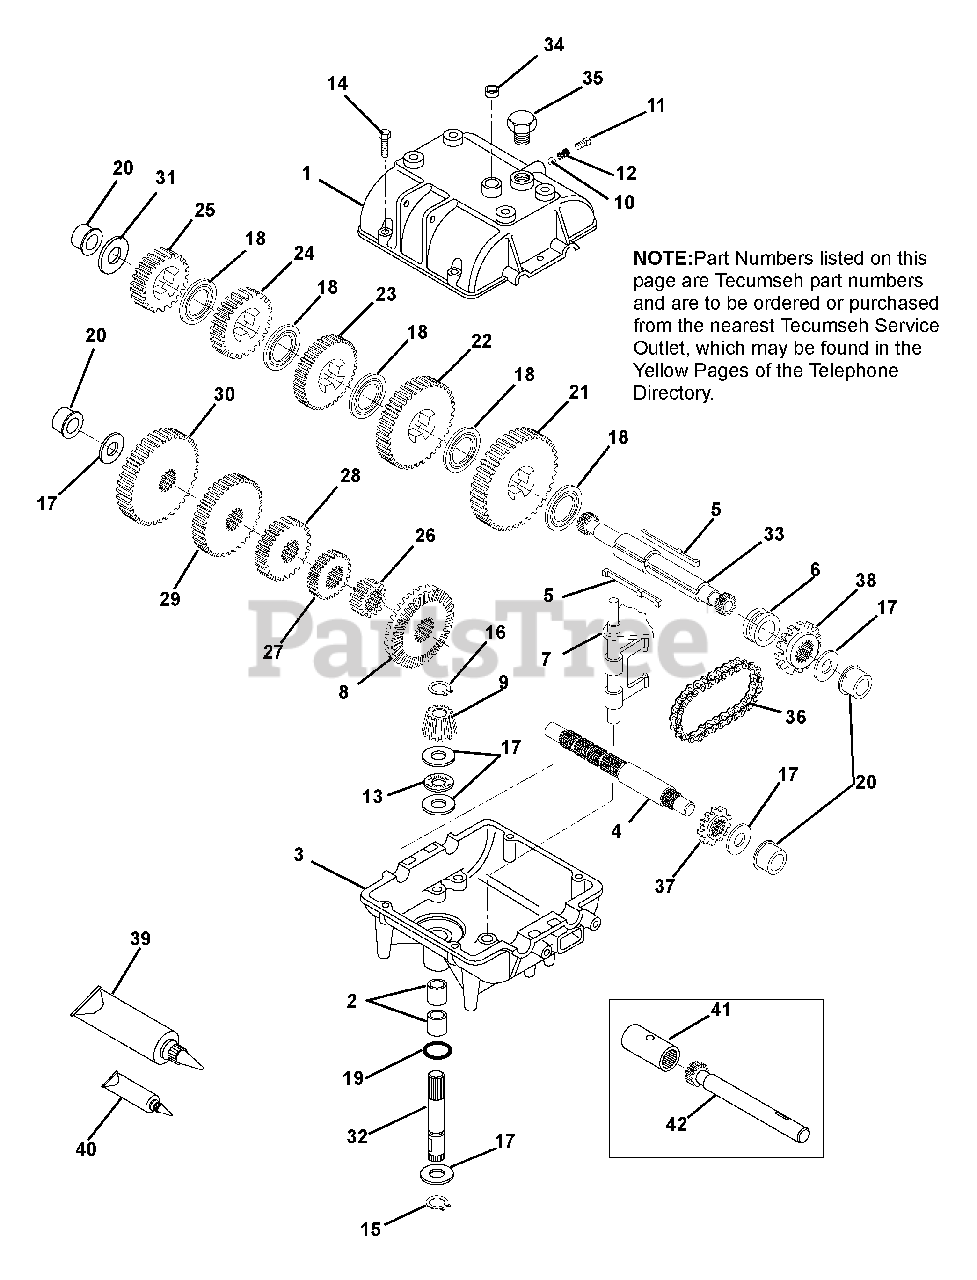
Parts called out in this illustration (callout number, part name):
1	Transmission Cover
2	Needle Bearing .625 ID x .50
3	Transmission Case
4	Countershaft
5	Shift Key
6	Shift Collar
7	Shift Rod & Fork Assembly
8	Bevel Gear (42 Teeth)
9	Bevel Pinion (14 Teeth-Steel)
10	Steel Ball .31 Diameter
11	Set Screw .38-16 x .38
12	Spring
13	Thrust Bearing
14	Screw .25-20 x 1.25
15	Ring, Retaining
16	Ring, Retaining
17	Washer
18	Washer
19	"O" Ring
20	Bushing, Flanged
21	Spur Gear (37 Teeth)
22	Spur Gear (35 Teeth)
23	Spur Gear (32 Teeth-Steel)
24	Spur Gear (30 Teeth)
25	Spur Gear (27 Teeth)
26	Spur Gear (12 Teeth)
27	Spur Gear (15 Teeth)
28	Spur Gear (18 Teeth)
29	Spur Gear (20 Teeth)
30	Spur Gear (23 Teeth)
31	Washer
32	Input Shaft 3.69 long
33	Shifter and Brake Shaft
34	Square Cut Ring
35	Threaded Plug
36	Roller Chain (No. 41, 24 Links)
37	Sprocket (9 Teeth)
38	Sprocket (18 Teeth)
39	Grease (32 oz. Bottle Bentonite Grease)
40	Gasket Eliminator (Loctite #515)
41	Optional Coupling (1.813 OD)
42	Optional Connector (6.095 long)
